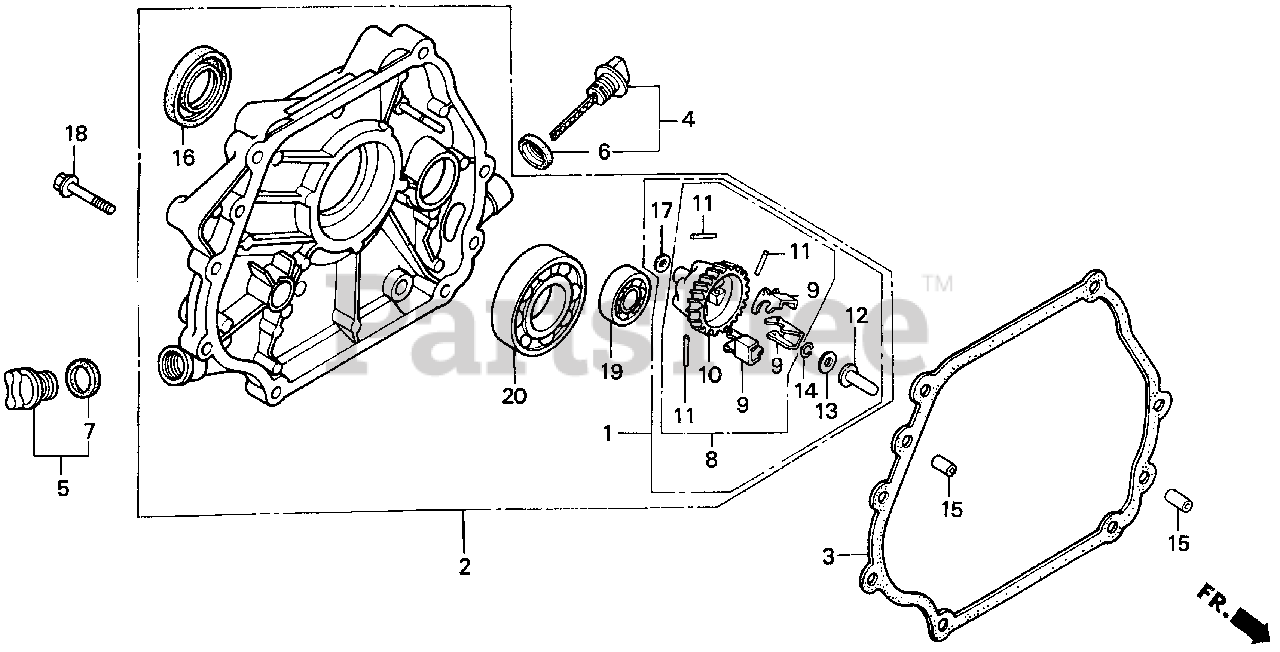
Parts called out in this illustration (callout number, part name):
1	GOVERNOR KIT
2	COVER ASSY., CRANKCASE (Q-TYPE)
3	GASKET, CASE COVER
4	CAP ASSY., OIL FILLER
5	CAP ASSY., OIL FILLER
6	GASKET, OIL FILLER CAP
7	GASKET, OIL FILLER CAP
8	GOVERNOR ASSY.
9	WEIGHT, GOVERNOR
10	HOLDER, GOVERNOR WEIGHT
11	PIN, GOVERNOR WEIGHT
12	SLIDER, GOVERNOR
13	WASHER (6X16)
14	CLIP, GOVERNOR HOLDER
15	PIN, DOWEL (8X12)
16	OIL SEAL (35X52X8)
17	WASHER, PLAIN (6MM)
18	BOLT, FLANGE (8X40)
19	BEARING, RADIAL BALL (6202)
20	BEARING, RADIAL BALL (6207)
